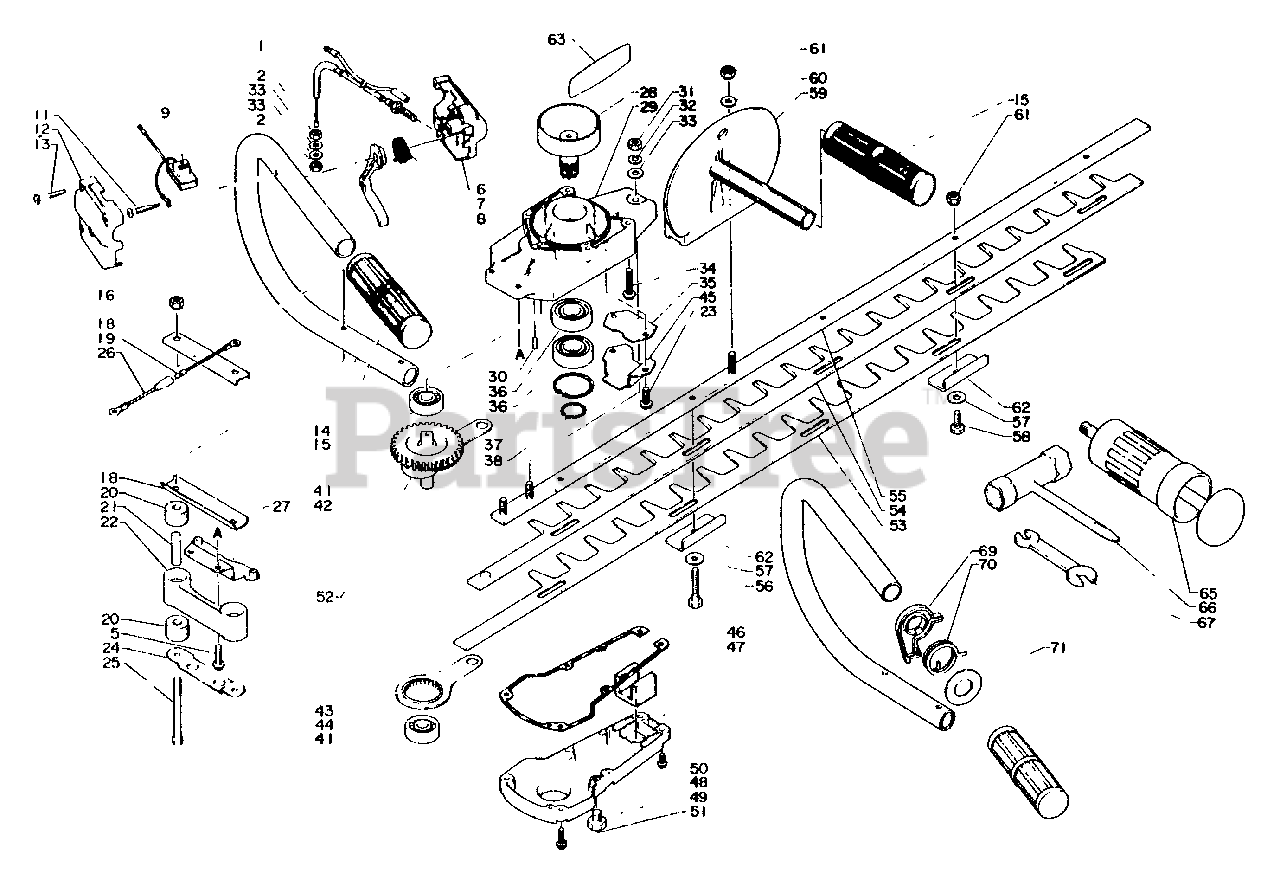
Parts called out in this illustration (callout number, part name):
1	CABLE, THROTTLE
5	SCREW - 5X16
6	BRACKET, THROTTLE CONTROL - RIGHT
7	SPRING, TRIGGER
8	TRIGGER, THROTTLE
9	IGNITION SWITCH ASSY
11	SCREW - 4X30
12	BRACKET, THROTTLE CONTROL - LEFT
13	SCREW - 4X25
14	HANDLE - REAR
15	GRIP, HANDLE
16	LOCKNUT - 5
18	BRACKET, HANDLE - LOWER
19	LEAD - GROUND
21	SPACER
22	BRACKET, HANDLE
23	SCREW - 5X14
24	PLATE, CUSHION
25	SCREW - 5X60
26	LEAD - GROUND
28	DRUM, CLUTCH
29	CASE, GEAR
30	PIN - LOCATING
31	LOCKNUT - 6
32	LOCKWASHER - 6
33	WASHER - 6
34	SCREW - 5X30
35	PLATE, GUIDE
36	BEARING, BALL - 6003
37	RING, RETAINING - 35
38	RING, RETAINING - 16
41	BEARING, BALL - 6200
42	GEAR
43	BEARING, NEEDLE
44	CONNECTING ROD ASSY
45	GUIDE
46	GASKET, GEAR CASE
47	SEAL, FELT
48	LID, GEAR CASE
49	BOLT - 8X8
50	SCREW - 4X14
51	SCREW - 4X22
52	GEAR ASSY
53	TRIMMER BLADE SET
54	TRIMMER BLADE SET
55	SUPPORT, BLADE
59	HANDLE - FRONT
60	WASHER - 6
61	LOCKNUT - 6
62	INSULATOR
63	LABEL - ECHO
65	PUMP, GREASE
66	T-WRENCH - 14X19mm
67	SPANNER - 8X10mm
69	LEVER, TRIGGER LOCKOUT
70	SPRING, LOCKOUT LEVER
71	SPACER
